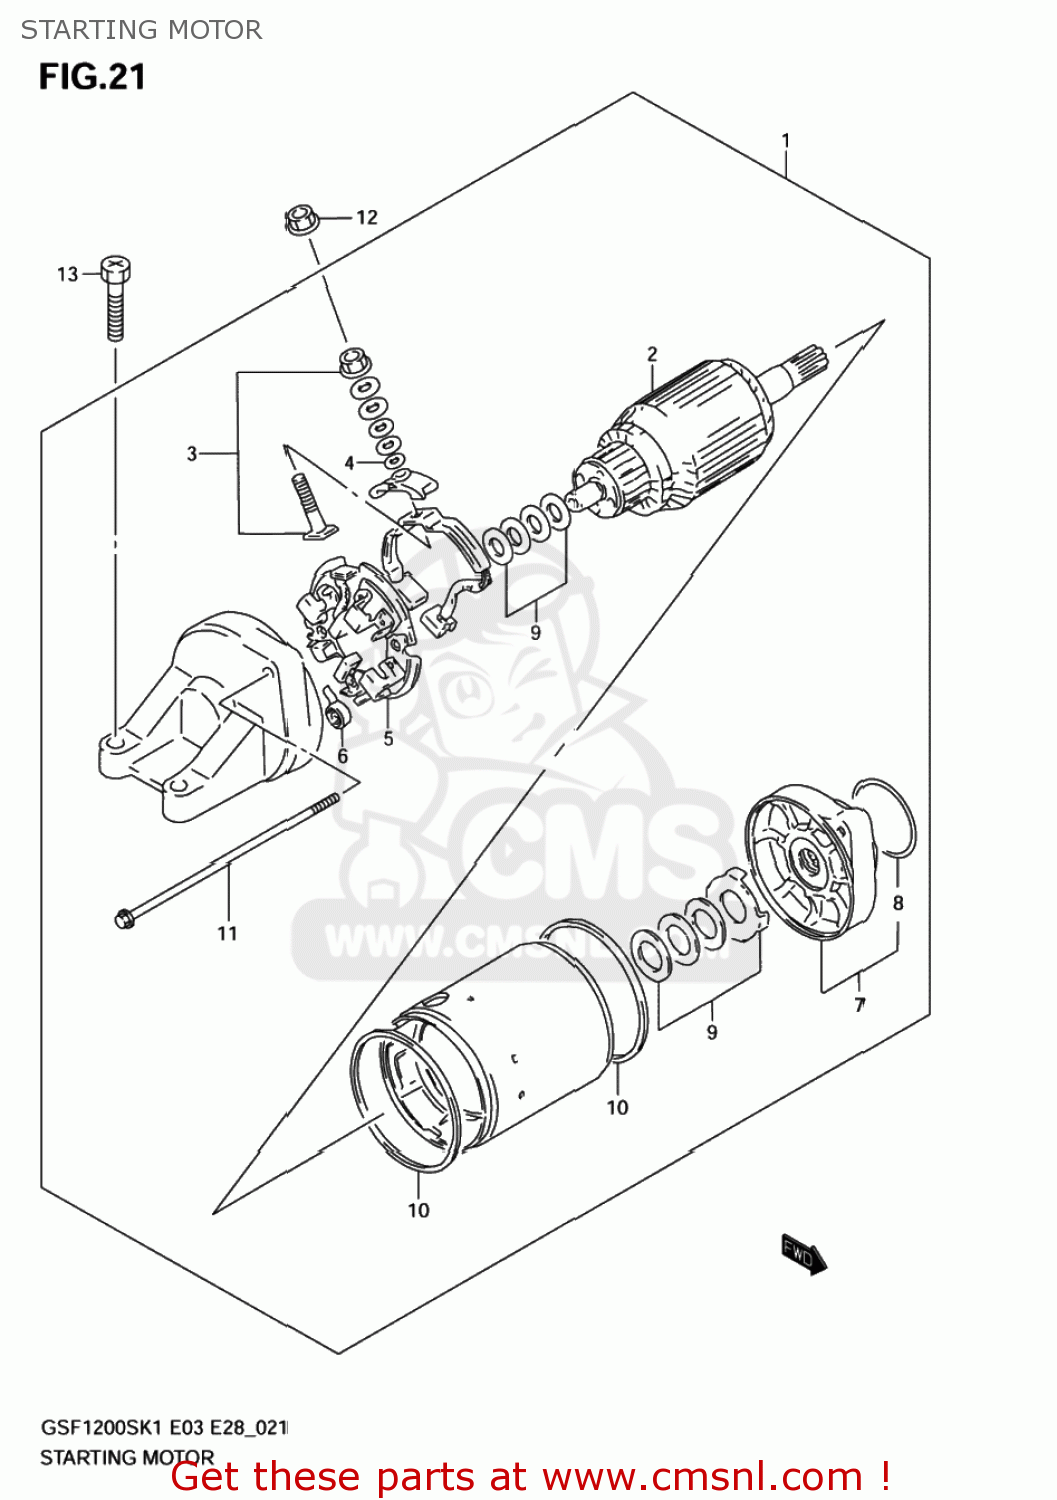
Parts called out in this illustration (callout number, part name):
1	MOTOR ASSY,STARTING
2	ARMATURE
3	TERMINAL SET,BRUSH
4	O RING
5	HOLDER SET,BRUSH
6	SPRING,BRUSH
7	BRACKET ASSY,FR
8	O RING
9	SHIM SET,STARTING MOTOR
10	O RING
11	BOLT
12	NUT
13	SCREW (6X25)
